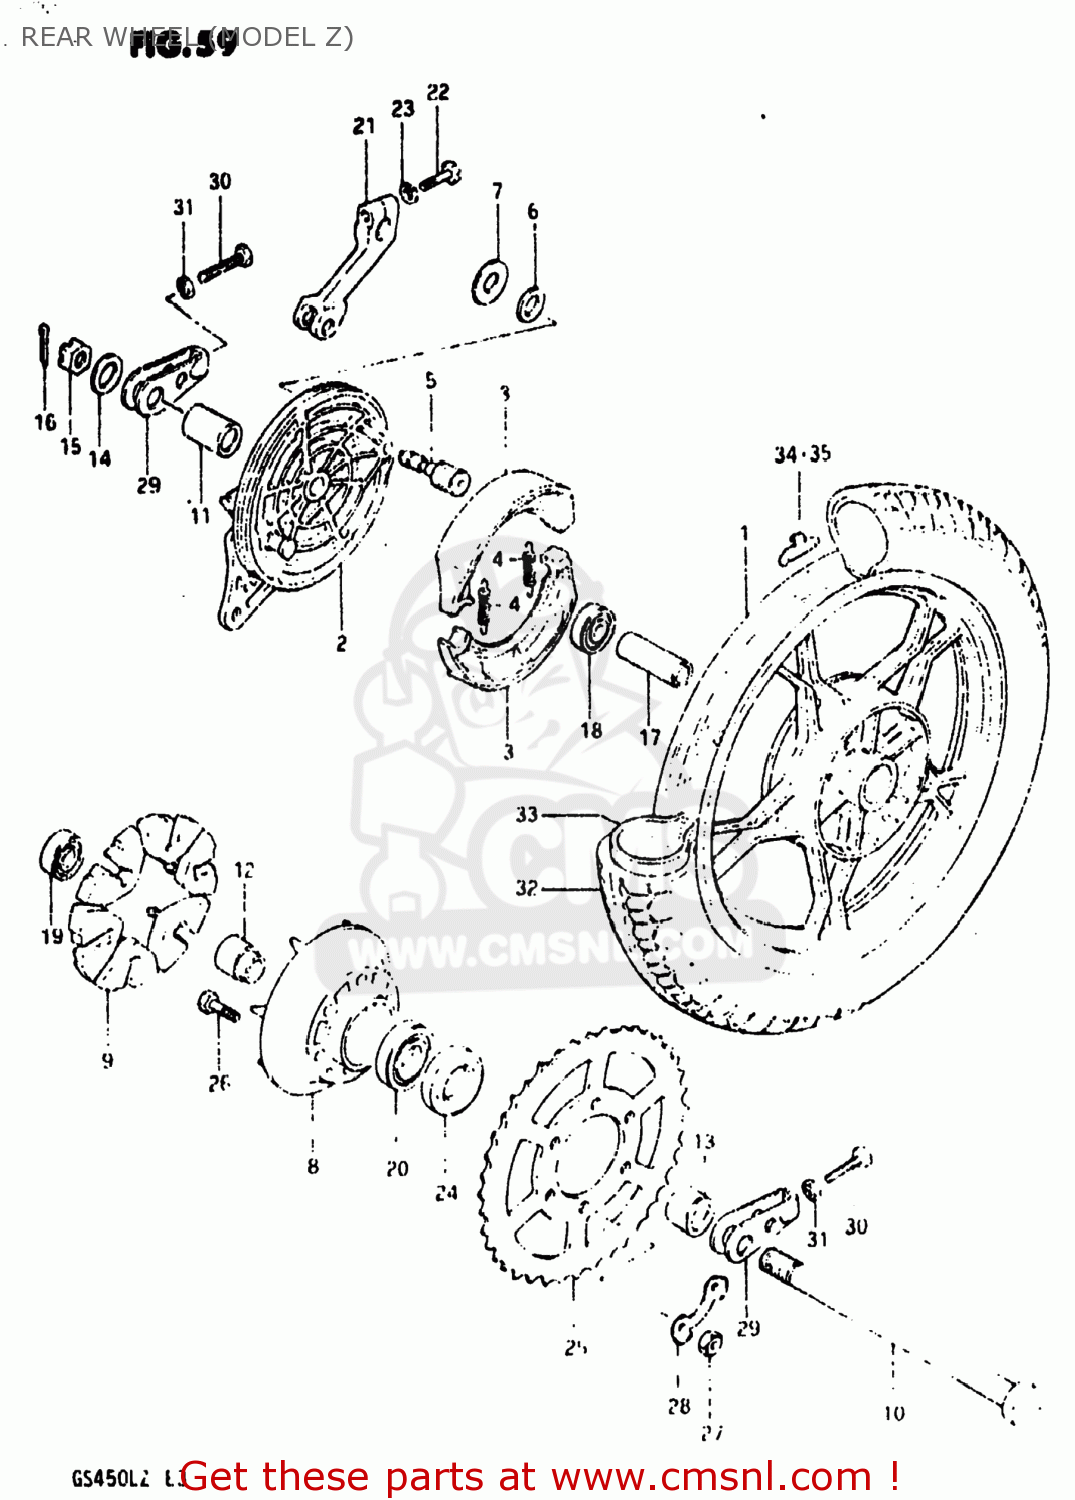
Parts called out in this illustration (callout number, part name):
1	CASTING WHEEL,REAR 2.15
2	PANEL,REAR HUB
3	SHOE,BRAKE
4	SPRING,BRAKE SHOE
5	CAM,FRONT BRAKE
6	O-RING,BOSS
7	WASHER (15X24X1.6)
8	DRUM,REAR SPROCKET MOUNT
9	ABSORBER,RR HUB SHOCK
10	AXLE,REAR
11	SPACER(17.5X28X44.8)
12	SPACER,REAR HUB BEARING
13	SPACER(17X30.5X22.3)
14	WASHER (17X30X3.2)
15	NUT
16	PIN,COTTER
17	SPACER (17.6X24X57)
18	BEARING
19	BEARING
20	BEARING
21	LEVER,RR BRAKE CAM
22	BOLT
23	LOCK WASHER
24	SEAL,OIL(30.5X52X8)
25	SPROCKET,REAR (NT:41)
26	BOLT
27	NUT
28	WASHER
29	ADJUSTER,CHAIN
30	BOLT 8X50
31	NUT
32	TIRE
33	TUBE ASSY,WHEEL,INNER 4.60-16
34	BALANCER,WHEEL
35	BALANCER,WHEEL
